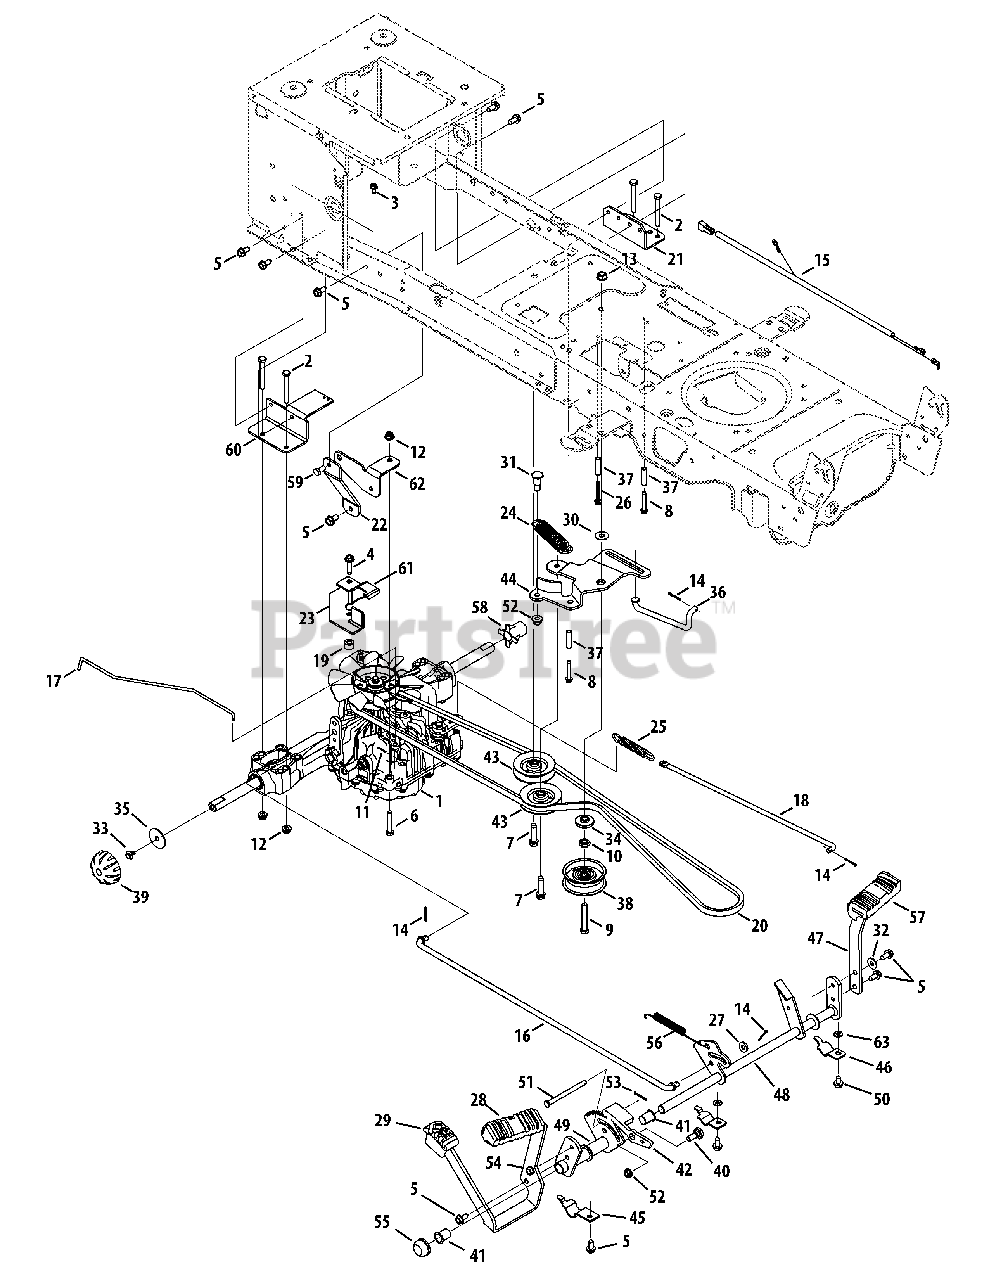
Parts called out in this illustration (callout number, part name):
1	Transmission, Tuff Torq K46
2	Hex Screw, 5/16-18, 2.50, Gr5, Std
3	Screw, Self-tapping, 1/4-20, 0.500
4	Screw, Self-tapping, 5/16-18, 1.250
5	Screw, Self-tapping, 5/16-18, .750
6	Hex Screw, 5/16-18, 1.75, Gr5
7	Screw, Self-tapping, 3/8-16, 1.500
8	Screw, Self-tapping, 1/4-20, 1.625
9	Hex Screw, 3/8-16, 2.25, Gr5
10	Nut, Jam, 7/16-20, Gr2
11	Pin, Cotter, 3/32, 1.0
12	Nut, Flange Lock, 5/16-18, Nylon
13	Nut, Flange Lock, 3/8-16
14	Pin, Cotter, 3/32, 1.0
15	Jumper Harness, Ground & Reverse
16	Rod, Control, Tuff-Torq
17	Rod, Hydro Bypass
18	Rod, Brake, NX9 Tuff-Torq
19	Spacer, .330 x .715 x .430
20	Belt, V-Type
21	Bracket, Mount, Tuff-Torq
22	Bracket, NX9 Tuff Torq
23	Bracket, Belt Keeper
24	Spring, Extension, 1.00 Dia x 4.75
25	Spring, Extension, .59 Od x 4.00
26	Screw, Self-tapping, 1/4-20 x 1.75
27	Washer, Flat, .375 x .738 x .063
28	Pad, Pedal, Forward
29	Pad, Pedal, Reverse
30	Wash, Flat, .385 x 1.00 x .030
31	Scr, Shldr, .50 x .685 3/8-16
32	Washer, Bell, .340 x .872 x .060
33	Screw, 5/16-24 x .750
34	Spacer, Shoulder, 1.375 x .380 x .183
35	Washer, Flat, .350 x 1.59 x .062
36	Rod, Transmission, Bypass
37	Spacer, .260 x .372 x 1.420
38	Pulley, Idler, Flat 2.75 OD
39	Cap, Hub
40	Bolt, Shoulder, .500 x .270, 3/8-16
41	Bearing, Flange, .630 x .695 x .60
42	Latch, Cruise
43	Pulley, Idler, V-Type x 3.06
44	Bracket, Idler, Center Double
45	Bracket, Support, Pedal Strap
46	Bracket, Support, Pedal Strap 5/8
47	Bracket, Pedal, Brake
48	Control Assembly, Brake
49	Bracket Assembly, Pedal, Hydro
50	Screw, Self-tapping, 5/16-18, 0.625,
51	Pin, Clevis, 5/16 x 3.985
52	Nut, Flange Lock, 3/8-16, Nylon
53	Pin, Cotter, Bow-Tie 72
54	Bracket, Pedal, Hydro
55	Cap, Push 5/8
56	Spring, Extension, .63 Dia x 4.95
57	Pad, Pedal, Brake
58	Sleeve, .765 Id x 1.500
59	Hex Cap Screw, 3/8-16 x .75
60	Bracket, Mount
61	Bracket, Belt
62	Bracket, Support
63	Flat Washer, .344 x .688 x .065
